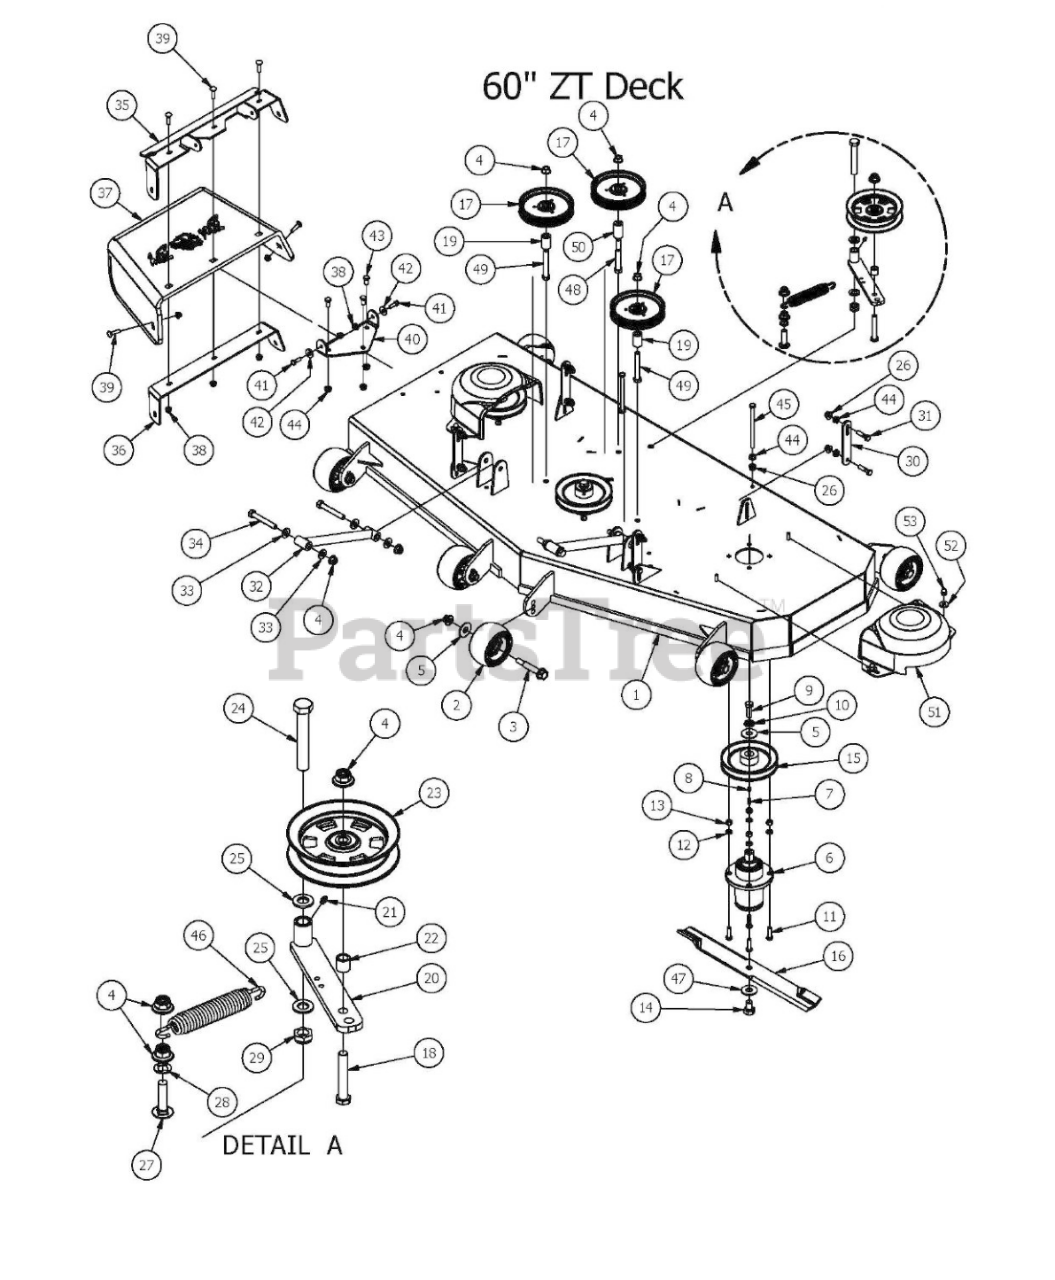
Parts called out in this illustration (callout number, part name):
1	60 ZT Welded Deck Shell
2	Deck Wheel
3	Deck Wheel Bolt
4	1/2-13 Nylon Flange Nut
5	1/2" Belleville Washer
6	Spindle Assembly
7	1/4" x 1" Key
8	5/16 Set Screw
9	1/2"-20 x 1 1/2 - Grade 5 Fine Thread Bolt
10	1/2" Lock Washer Zinc
11	3/8" x 1 1/4" Hex Bolt
12	3/8" Lock Washer
13	3/8" Hex Nut
14	5/8" x 1 1/2" Grade 8 Hex Bolt (Fine)
15	6 1/4" Drive Pulley
16	60 Inch Fusion Blade
17	5-3/4 Idler Pulley-Capitol Stampings
18	1/2-13 x GR 5 Hex Bolt Zinc
19	Idler Pulley Standoff
20	Deck Idler
21	1/4" Press in Grease Fitting
22	Spacer 3/4 OD x 1/2 ID x 314 Length
23	5" Idler Pully
24	5/8" x 4" Hex Bolt
25	.630 ID Plastic Washer
26	3/8 Nylon Flange Nut
27	1/2 x 2" Carriage Bolt
28	.517 Square Hole Round Washer
29	5/8-11 Nylon Insert Jam Half Nut
30	2017 MZ/ZT Deck Hanger
31	3/8" x 1 1/2" Hex Bolt
32	MZ/ZT Deck Locator
33	.505 Nylon Spacer
34	1/2-13 x 3 1/2 GR 5 Hex Bolt
35	Discharge Upper Chute Bracket
36	Discharge Lower Chute Bracket
37	Rubber Discharge Chute
38	5/16" Nylon Flange Nut
39	5/16" x 1 1/4" Carriage Bolt
40	Discharge Chute Hanger (Deck Mounted)
41	5/16" x 1" Bolt
42	.360 ID Plastic Washer
43	3/8" x 3/4" Hex Bolt
44	3/8" Flange Nut
45	3/8-16 x 5 1/2 Hex Bolt
46	2015 Deck Idler Spring
47	5/8" Flat Washer
48	1/2" x 4" Bolt (Grade 8)
49	1/2 x 3 1/2 Flange Bolt Grade 8
50	1 3/4" Pulley Spacer
51	Pulley Cover
52	.360 ID Plastic Washer-Black
53	Acorn nut-pulley Cover
